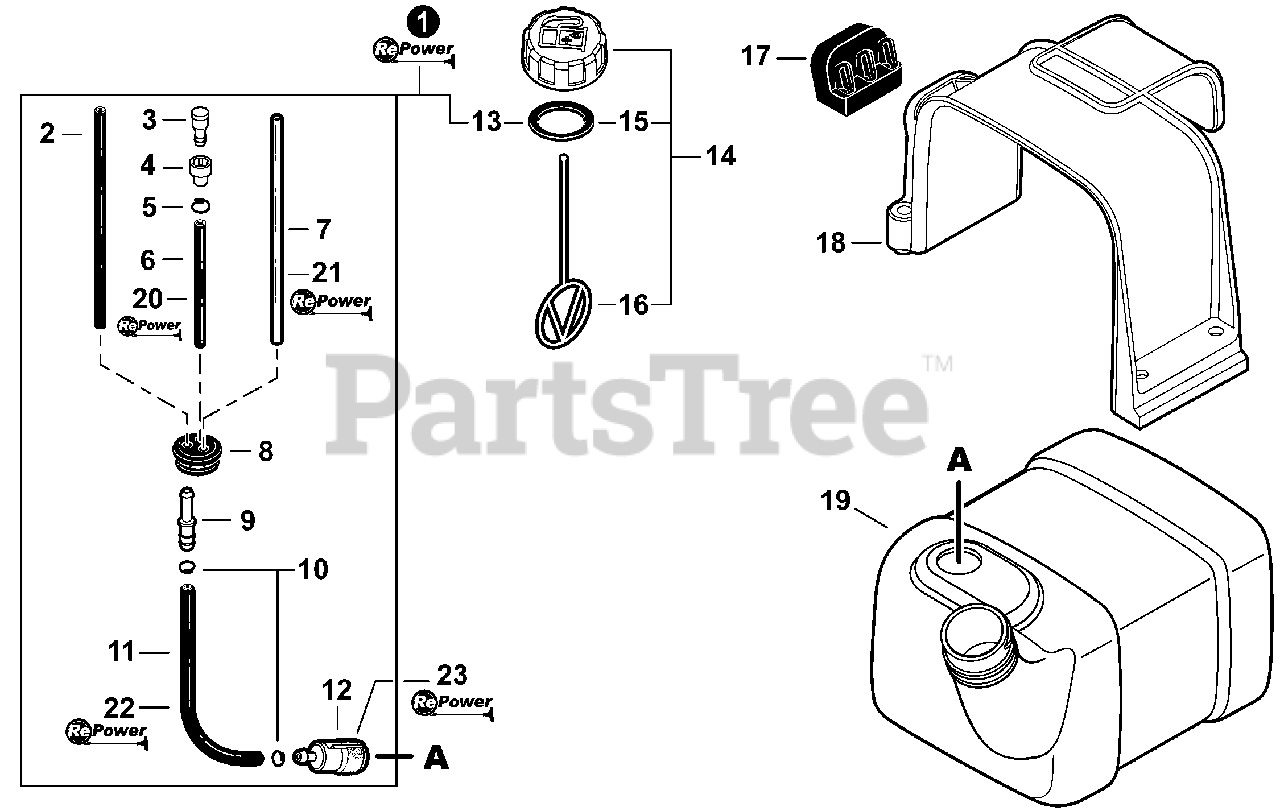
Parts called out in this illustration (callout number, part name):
1	FUEL SYSTEM KIT - REPOWER
2	PIPE, FUEL 3×5×205 BLACK
3	VENT ASSY
4	HOLDER, VENT
5	CLIP Ø6.5MM
6	PIPE, FUEL 3×6×40 BLACK
7	PIPE 3×6×180 CLEAR
8	GROMMET, FUEL
9	CONNECTOR, PIPE Ø5ר3.5
10	CLIP Ø6
11	PIPE, FUEL 3×5×120 BLACK
12	FILTER, FUEL
13	GASKET, FUEL CAP
14	CAP ASSY, FUEL
15	GASKET, FUEL CAP
16	CONNECTOR, CAP L= 100mm
17	CUSHION
18	RETAINER, FUEL TANK
19	TANK, FUEL
20	PIPE, BULK - 3×6mm BLACK
21	PIPE, BULK - 3×6mm CLEAR
22	PIPE, BULK - 3×5mm BLACK
23	TUNE-UP KIT - REPOWER
